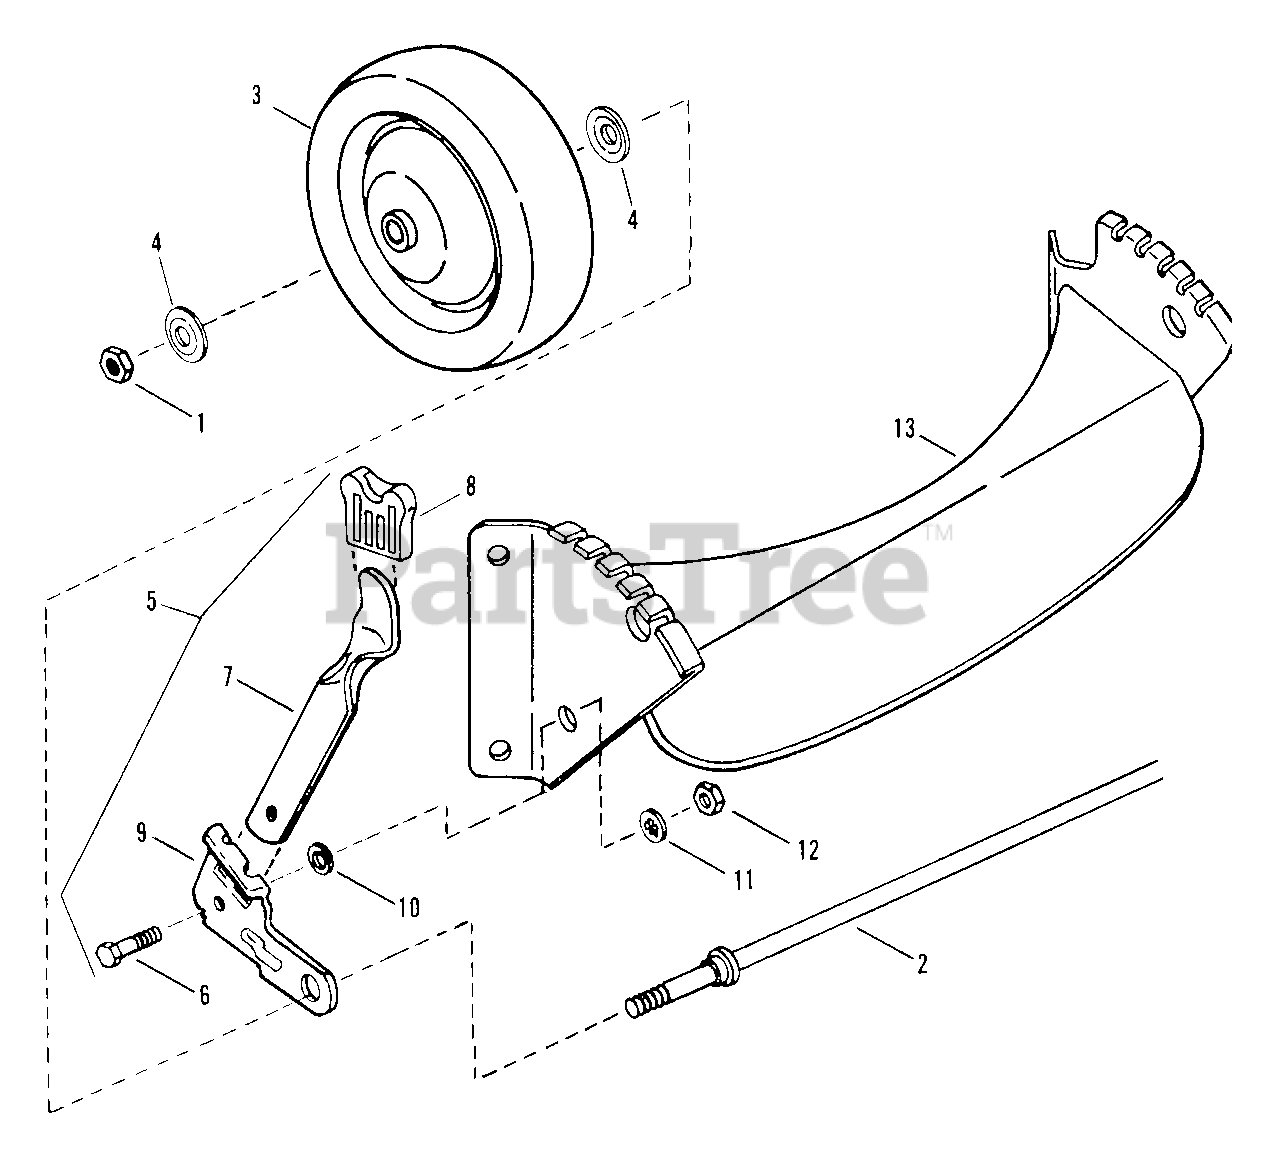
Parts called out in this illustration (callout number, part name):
1	NUT, 7/16-20 Hex Centerlock
2	AXLE
3	WHEEL, Front, 7 x 1.75 Steel Rim
4	HUB-CAP
5A	ARM ASSEMBLY, Left Wheel
5B	ARM ASSEMBLY, Right Wheel
6	BOLT, 5/16-18 Shoulder
7	LATCH, Height
8	GRIP
9A	ARM, Left Wheel
9B	ARM, Right Wheel
10	RETAINER, 5/16 Bolt
11	WASHER, 5/16 Int. Toothlock
12	NUT, 5/16-18 Hex
13	BRACKET, Front Wheel
